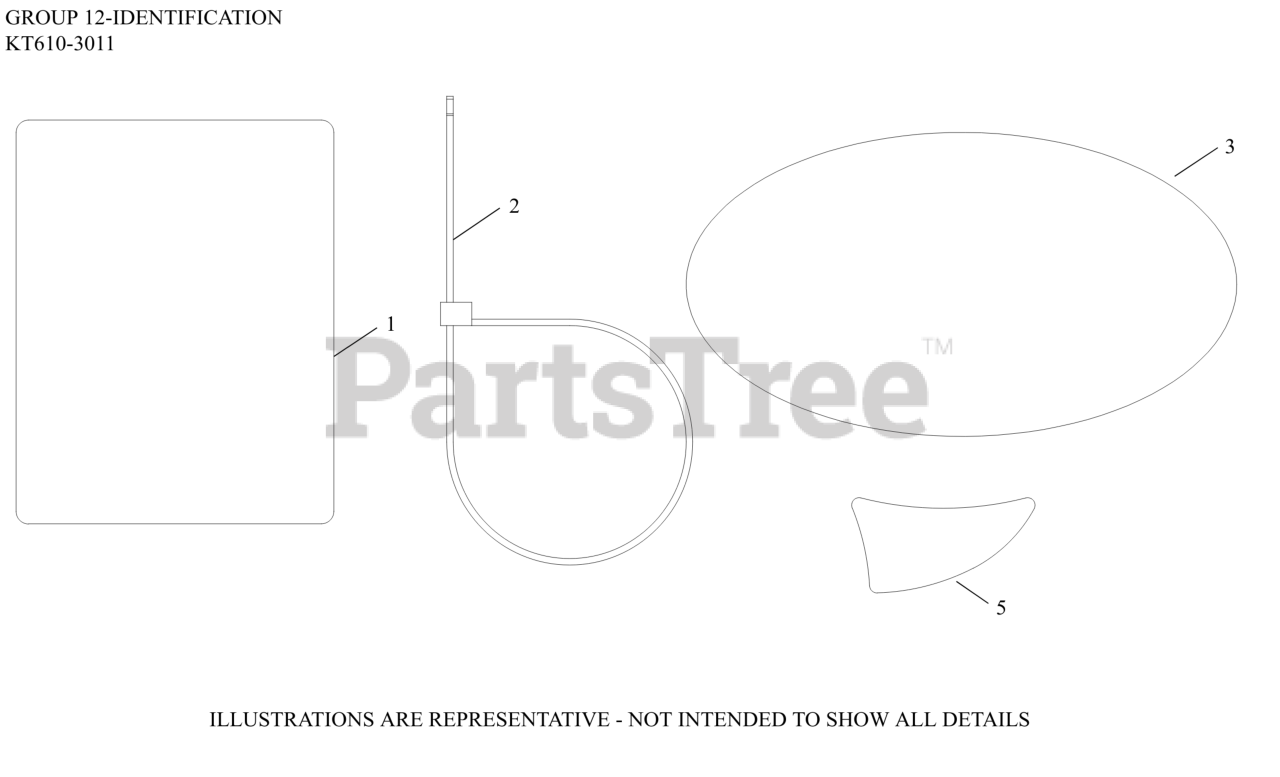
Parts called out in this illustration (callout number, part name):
1	LABEL, CLEAR LAMINATION
3	LABEL, 6600 SERIES (19HP)
3	LABEL, PRO PERFORMANCE FILTRATION SYSTEM
5	LABEL, SMART CHOKE
